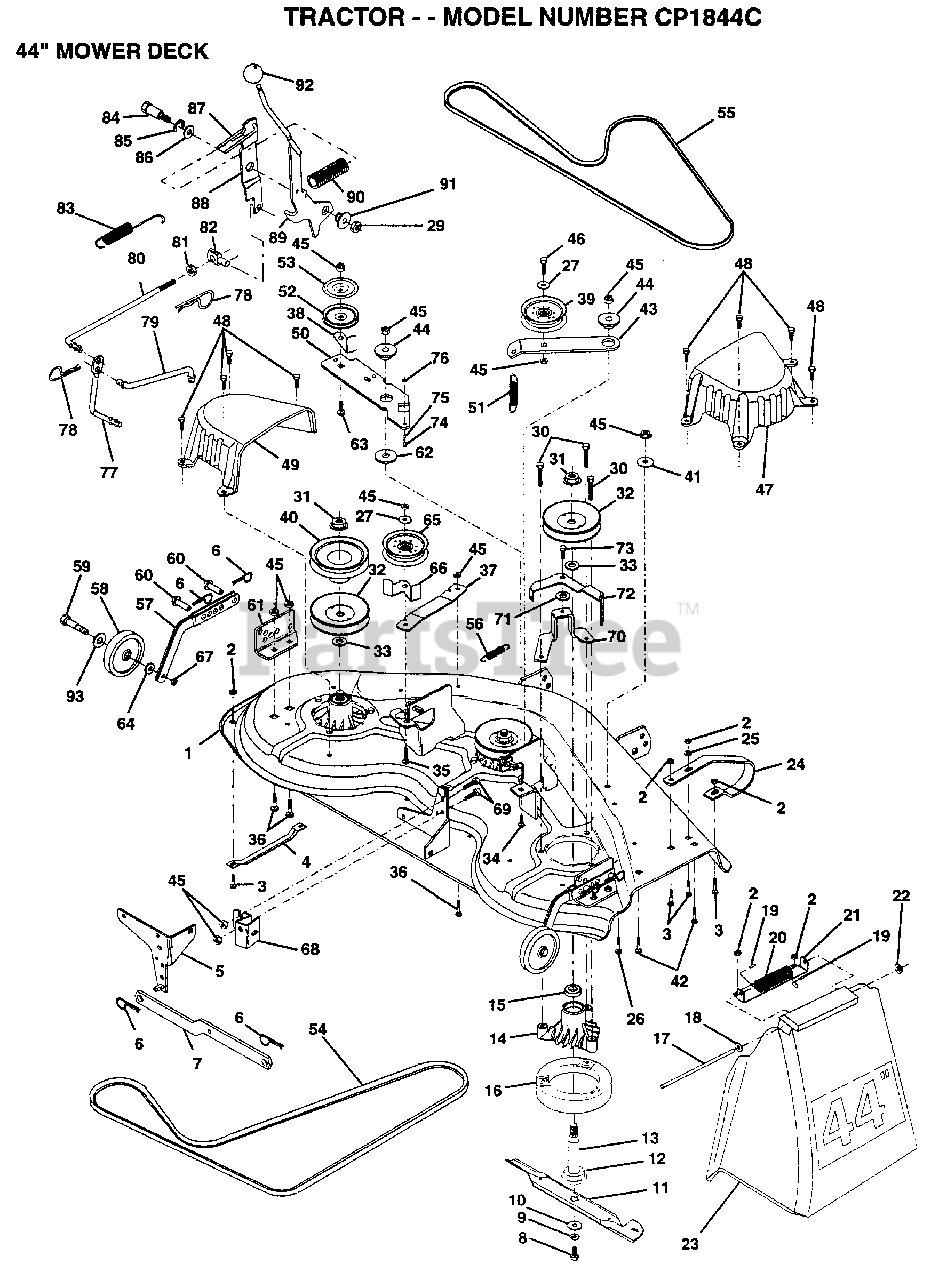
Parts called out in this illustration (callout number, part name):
1	"DECK ASM WELD44"""
4	RUNNER-LH M
5	BRKT.ASM.SW.44/50
8	BLADE BOLT
10	WASHER.HARD.BLADE
11	"BLADE.44"" HIPERF"
12	BEARING.BALL
13	SHAFT.ASM.W/BRNG
14	HOUSING.MAND.44.V
15	BEARING
16	STRIPPER RND MWR
17	ROD-HINGE T
18	WASHER
19	CAP-SLEEVE LT
20	SPRING TORSION
21	BRKT DEFLECTOR
22	NUT PUSH M
23	DEFLECTOR SHIELD
24	RUNNER.RH
25	WASHER M
27	WASHER
29	NUT
33	WASHER
34	BOLT.3/8-14X1.25
35	BOLT
36	BOLT D
37	STIFFENER.ARM.IDL
38	KEEPER BELT IDLER
39	FLAT IDLER PULLEY
40	"PULLEY.DRIVEN.44"""
42	BOLT
43	"ARM.IDLER.SEC.44"""
44	SPACER RETAINER
47	"COVER.MAND.RH.44"""
48	SCREW.1/4-20X5/8
49	COVER.MANDREL.LH
50	ARM.IDLER.PRIMARY
51	"SPRING.SEC.44""VEN"
52	PULLEY.IDLER.VGRO
53	SHIELD.IDLER.44.V
54	BELT-V MOWER PRIM
55	BELT-V.88.12.MW
56	"SPRING,EXTENTION"
57	BAR.ASM.GUAGE.WHL
58	WHEEL.GAGE.BLK.PL
59	BOLT M
60	PIN.CLEVIS
61	BRACKET.GUAGE.WHL
62	HARDENED WASHER
63	BOLT.3/8-16X1.50
64	WASHER
65	IDLER-FLAT T
67	LOCKNUT
68	BRACKET PVT MCH
70	"BRACKET SUPT 44"""
71	HARD SMALL WASHER
72	ARM BRAKE ASM
73	BOLT.SHLD.5/16-18
75	SHOULDER BOLT
76	LOCKNUT
77	PIVOT ROD
78	RETAINER M
79	ROD CLUTCH SECON
80	ROD.CLUTCH.PRIM44
81	NUT
82	TRUNION ADJ
83	RETURN SPRING
84	SHOULDER BOLT
85	RING
86	WASHER
87	SPRING KEEPER
88	CLUTCH ARM SECOND
89	LEVER.CLU.PRIM.
91	BUSHING
